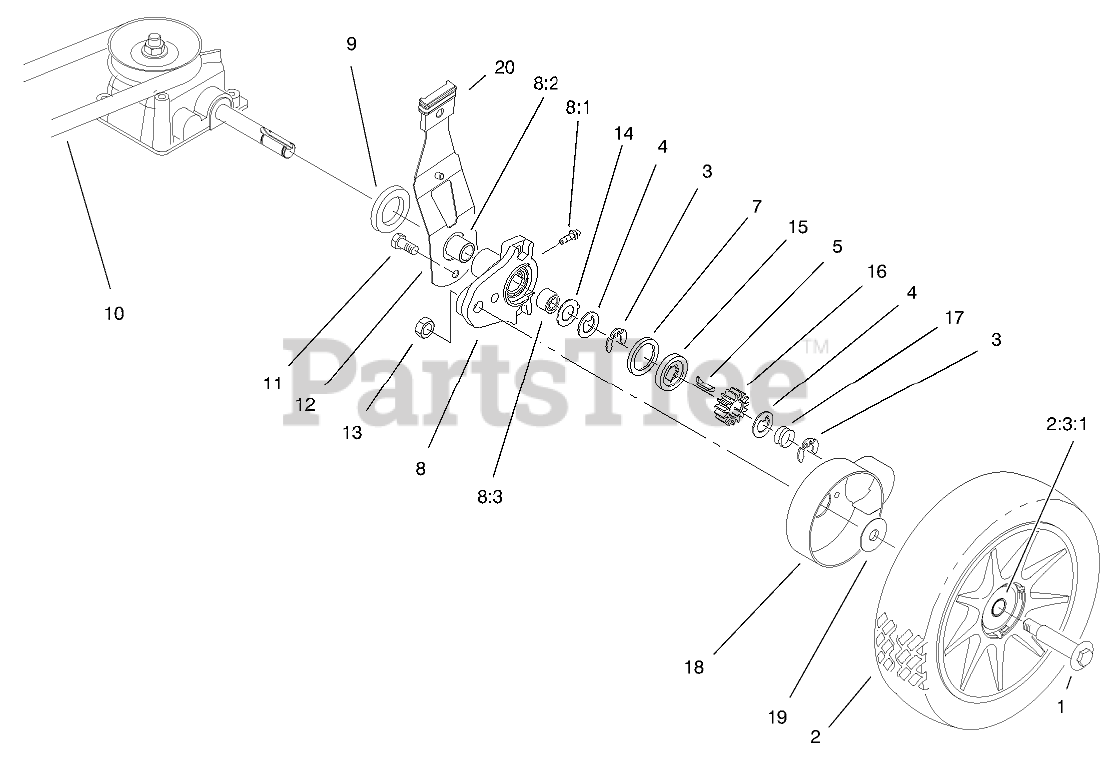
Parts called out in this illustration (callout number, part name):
1	BOLT-SHOULDER
2	WHEEL AND TIRE ASM
2:3	8" Wheel & Tire ASM
2:3:1	BUSHING
3	RING-CLIP, LOCKING
4	WASHER-THRUST, KEYED
5	KEY-ROCKING, LH
6	KEY-ROCKING, RH
7	RING-FRICTION
8	REAR HEIGHT ADJUSTMENT ARM ASM
8:1	FITTING-GREASE
8:2	BUSHING
8:3	BUSHING
9	SPACER-AXLE SHAFT
10	V-BELT
11	SCREW-HWH
12	REAR SPRING ARM ASM
13	NUT-JAM, LOCKING
14	WASHER-ARM, PIVOT
15	WASHER-CLUTCH
16	GEAR-PINION
17	SPRING-COMPRESSION
18	COVER-WHEEL
19	WASHER-STEPPED
20	KNOB-LEVER, HEIGHT ADJUSTMENT
